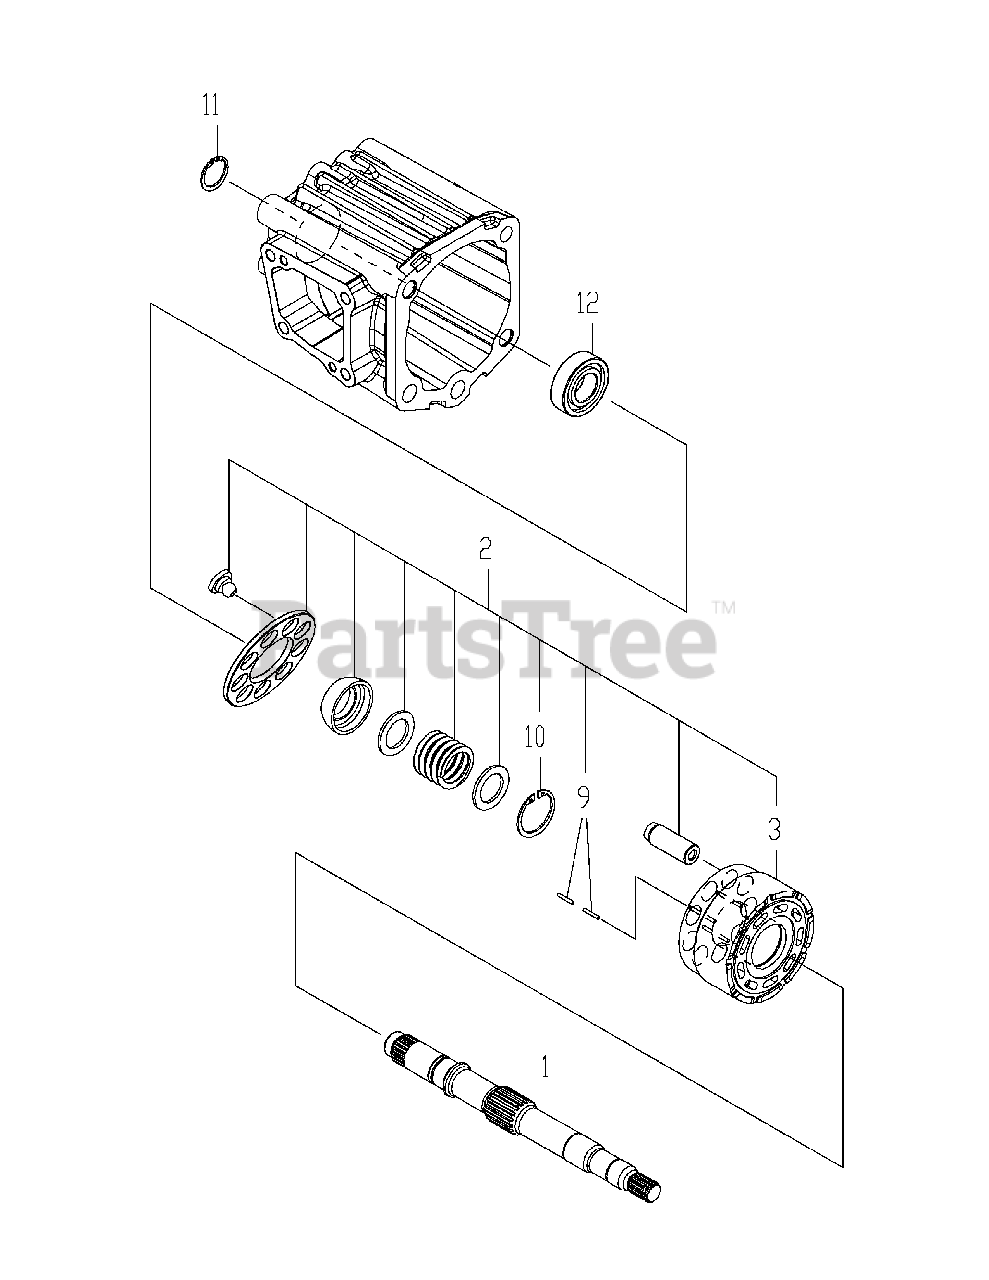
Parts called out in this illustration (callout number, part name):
1	MOTOR SHAFT (K93
2	BLOCK ASSY, CYL
3	BLOCK, CYLINDER
12	BEARING, 6004U
